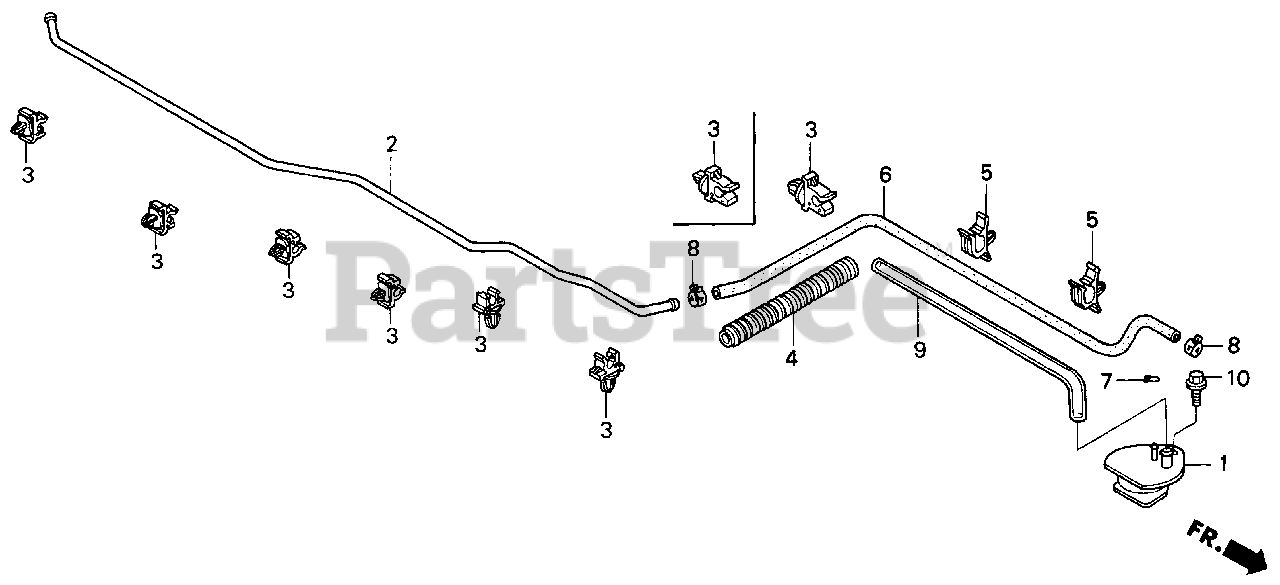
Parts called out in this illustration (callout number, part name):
1	TANK, FUEL CATCH
2	PIPE, FUEL FEED
3	CLAMP, FUEL VENT PIPE
4	TUBE, CORRUGATED (C)
5	CLIP, WIRE HARNESS
6	BULK HOSE, FUEL (4.5X3000) (4.5X335)
7	CLIP, TUBE (B8)
8	CLIP, TUBE (D8.5)
9	BULK HOSE, VINYL (8X12X8000) (8X12X200)
10	BOLT, FLANGE (8X16)
